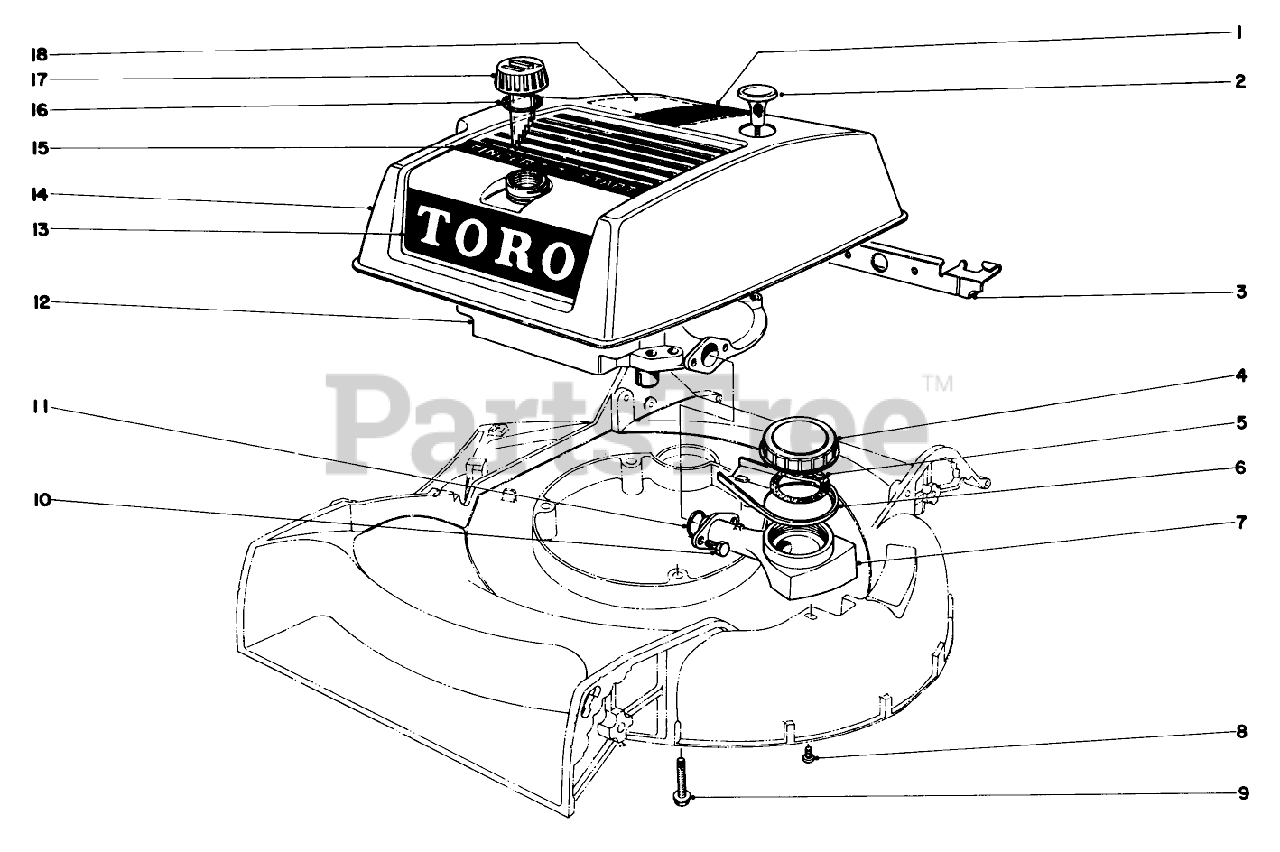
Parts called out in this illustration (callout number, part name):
1	Decal
3	Shroud Bracket
7	Oil Gauge
9	3/8-16 X 2-3/4 CAPSCR
10	SCREW-HH
11	O RING
12	Engine
13	Decal-Toro
15	Decal
16	Gasket
18	Decal-Maintenance
